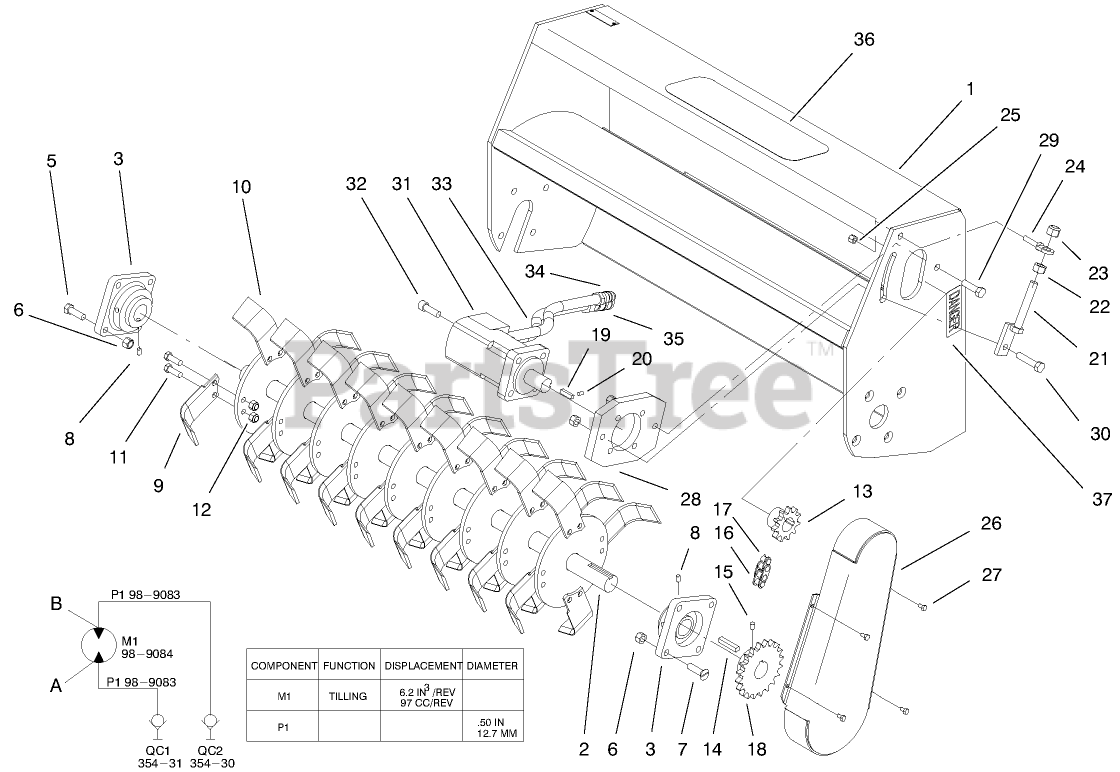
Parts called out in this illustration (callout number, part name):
1	Tiller Frame Asm (Incl. Ref. #37)
2	SHAFT-TINE
3	BEARING ASM
5	SCREW-HH
6	NUT-LOCK, NI
8	SCREW-SET
9	Tine-RH
10	Tine-LH
11	SCREW-HH
12	NUT-LOCK, INSERT
13	SPROCKET-11 TOOTH
14	KEY-SQUARE
15	SCREW-SET
16	CHAIN-ROLLER
17	LINK-CONNECTING
18	SPROCKET-20 TOOTH
19	KEY-SQUARE
20	SCREW-SET
21	CHAIN ADJUSTMENT ASM
22	NUT-HEX
23	NUT-LOCK NI
24	HOLDER-ADJUSTMENT
25	NUT-LOCK, NI
26	COVER-CHAIN, TILLER
27	SCREW-HH
28	PLATE-MOUNT, MOTOR
29	SCREW-HH
30	SCREW-HH
31	MOTOR-HYD
32	SCREW-HSH
33	HOSE - HYDRAULIC
34	QUICK COUPLER - MALE
35	QUICK COUPLER - FEMALE
36	DECAL - FRONT
37	DECAL-DANGER
